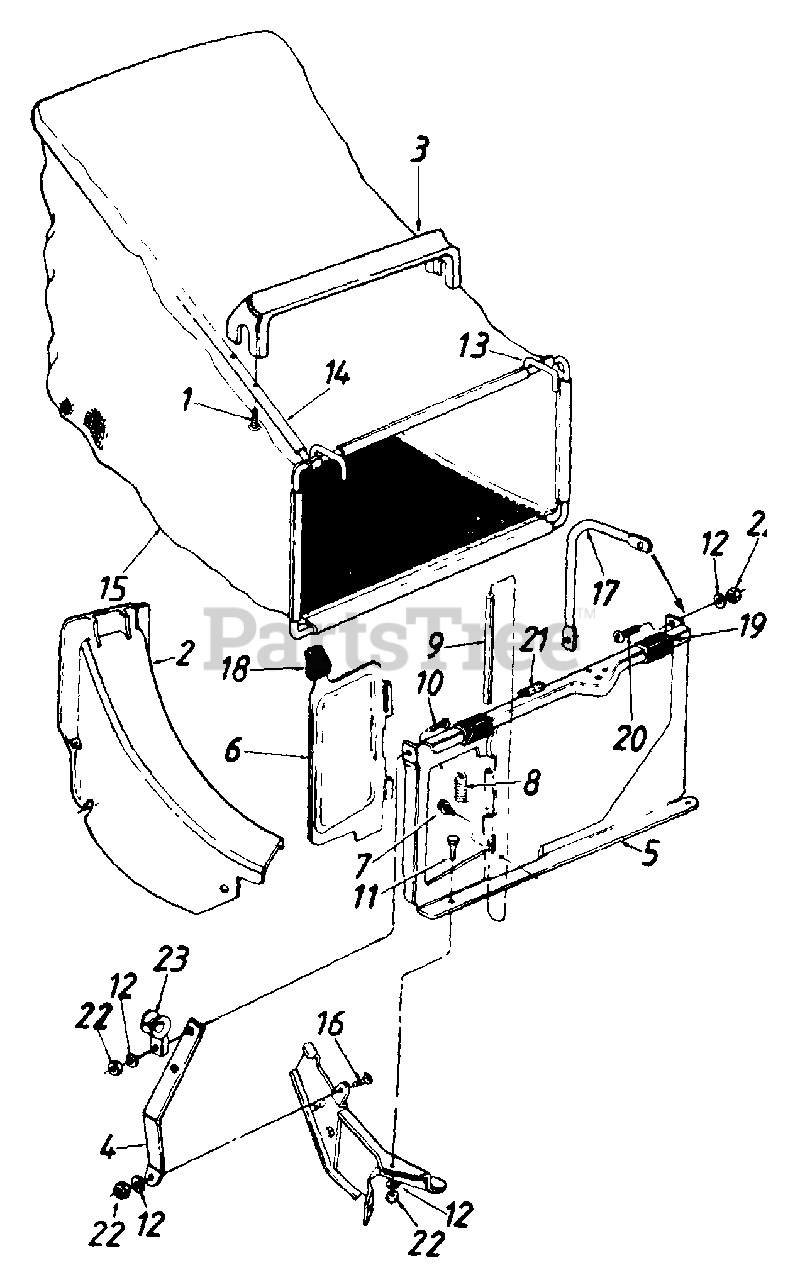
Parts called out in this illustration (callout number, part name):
1	Hex AB-Tap Scr. #12 x 1.25" Lg.
2	Rear Discharge Chute Ass'y.
3	Bag Handle
7	Hex B-Tap Scr. #10 x 38"
8	Torsion Spring
9	Pivot Pin
10	Truss Mach. Scr. 1/4-20 x 3/4" Lg.
11	Hex Bolt 1/4-20 x .50" Lg.
12	L-Wash. 1/4" I.D.
15	21" Rear Discharge Grass Bag
16	Hex Bolt 1/4-20 x 62" Lg.
17	Catcher Panel Support Arm
18	Door Grip
19	Panel Clip
20	Truss Mach Scr. 1/4-20 x .62" Lg.
21	Foam Strip
22	Hex Nut 1/4-20 Thd
23	Rope Guide
